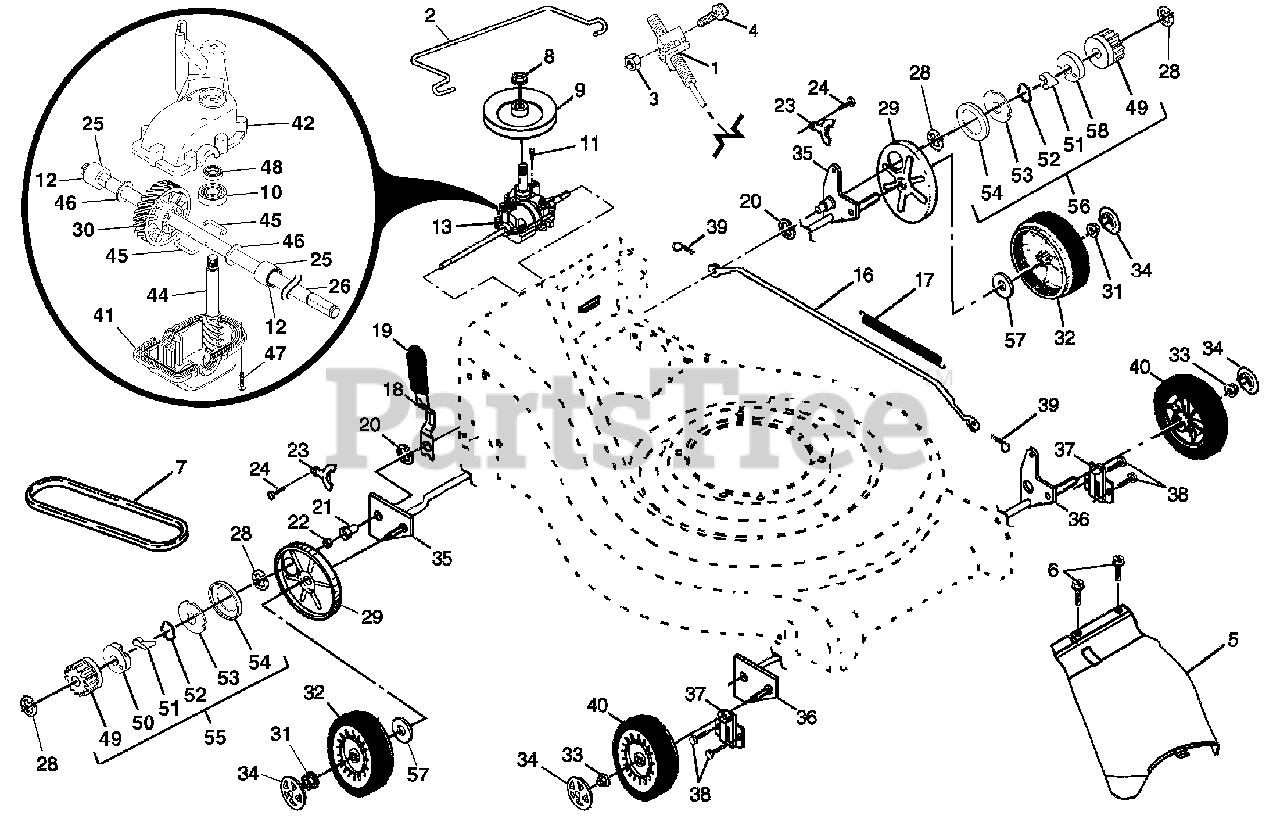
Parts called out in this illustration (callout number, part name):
1	Handle, Upper
2	Handle, Lower
3	Spring, Rear Door, RH
4	Guide, Rope, Side
5	Nut, Hex, with Lockwasher Insert 1/4-20
6	Wire, Tie
7	Bolt, Handle 5/16-18 x 2-5/8
8	Knob, Handle
9	Control Bar
10	Bolt, Carriage
11	Nut, Hex, with Lockwasher Insert 5/16-18 UNC
12	Cotter, Hairpin
13	Spring, Rear Door, LH
14	Spring, Rear Door, RH
16	Rear Door Assembly
17	Bolt, Rear Door
18	Plug, Mulcher
19	Kit, Housing
20	Handle Bracket Asembly, Left
21	Handle Bracket Assembly, Right
22	Screw, Hex Washer Head
23	Bolt, Hex Head 5/16-18 x 5/8
24	Nut, Hex, with Lockwasher Insert 5/16-18
25	Baffle, Side
26	Screw #12 x 5/8
27	Skirt, Rear
28	Screw, Hinge 1/4-20 x 1.25
29	Cable, Engine Zone Control
31	Blade, 21"
34	Bolt, Hex Head
37	Bolt, Engine
39	Grassbag
40	Frame, Grassbag
41	Danger Decal
57	Bracket Assembly
58	Screw
59	Pulley
61	Nut, Hex, Flanged
62	Locknut
63	Idler Arm
64	Idler Pulley
65	Shoulder Bolt
66	Rear Door Assembly
67	Mulcher Door, Multi-Cut
68	Nut, Hex
76	Bracket, Upstop
77	Screw
87	Washer
88	Washer, Lock
89	Blade Adapter / Pulley
90	Debris Shield
91	Bolt
92	Mounting Bracket, Debris Shield
92	Operator's Manual, English
92	Operator's Manual, French
92	Repair Parts Manual, English / French
